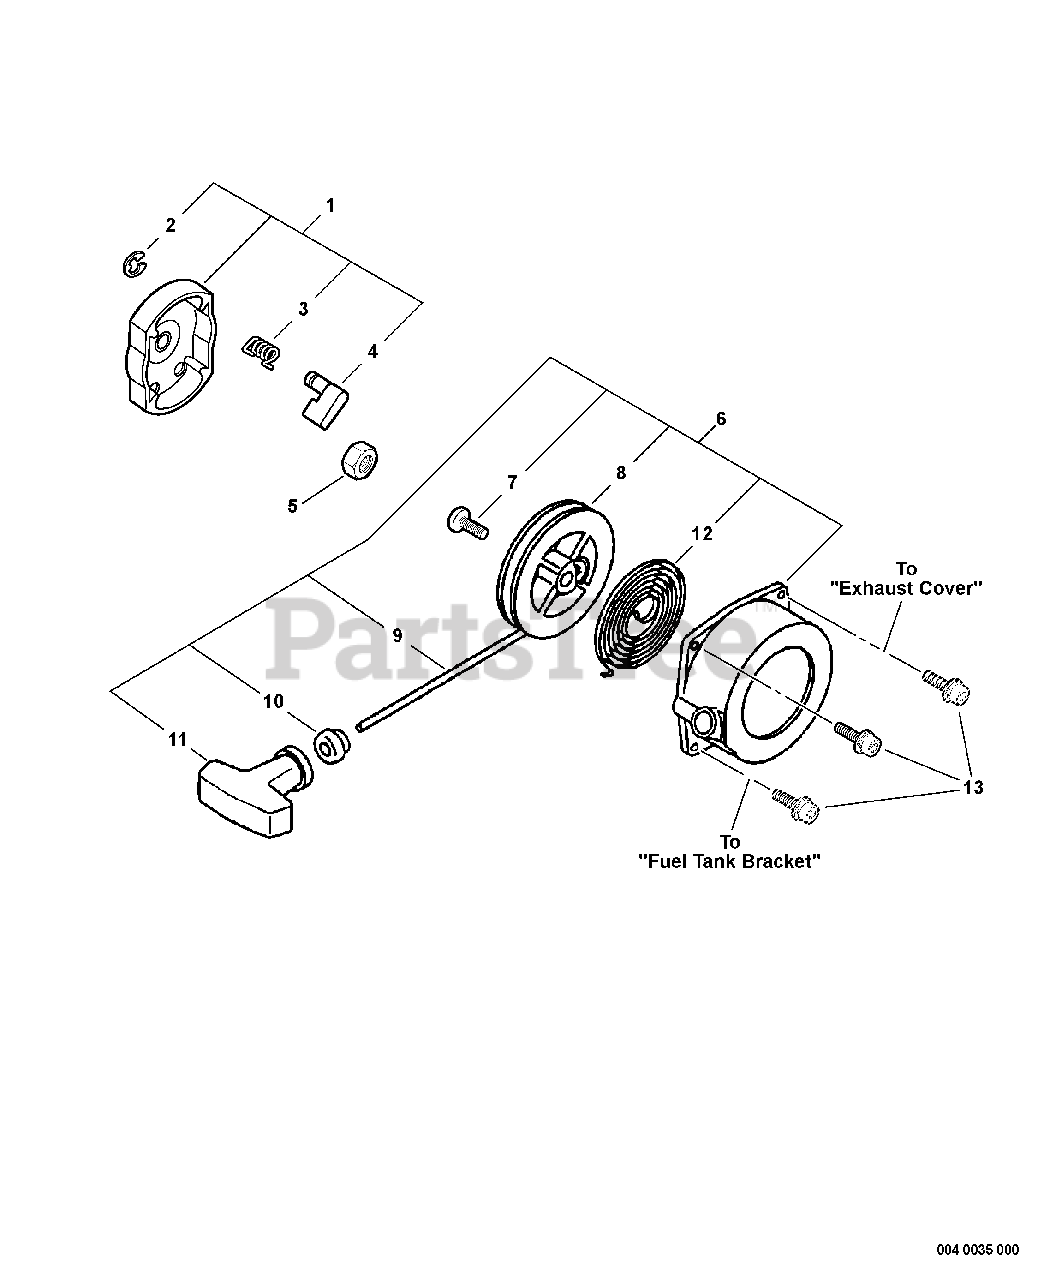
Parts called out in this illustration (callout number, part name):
1	PULLEY ASSY, STARTER
2	E-RING 4
3	SPRING, RETURN
4	PAWL, STARTER
5	NUT 8×1.25
6	STARTER ASSY, RECOIL
8	REEL, ROPE
9	ROPE, STARTER 3.8×1150
10	GUIDE, ROPE
11	GRIP, STARTER
12	SPRING, RECOIL
13	BOLT 5×20
